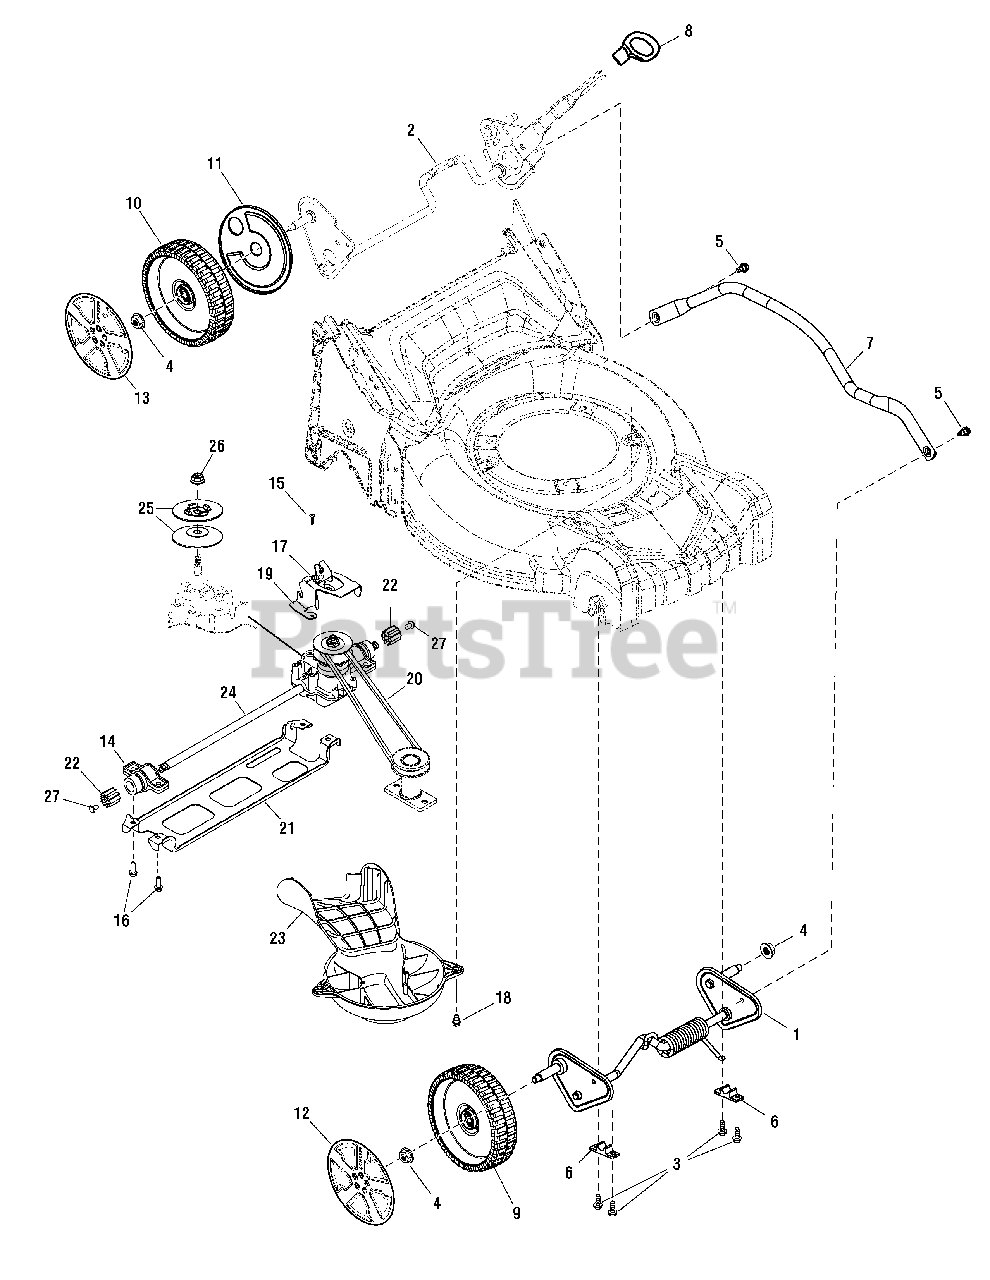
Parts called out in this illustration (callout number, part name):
1	AXLE, Front
2	AXLE, Rear
3	SCREW, 1/4-15X3/4, Self-Tapping, BZ
4	NUT, Hex Flange, Nylock, 3/8-16
5	SCREW, 1/4-20 x 1/2
6	BUSHING, Lock
8	KNOB, Red
9	WHEEL, 180 x 47
10	WHEEL, Drive
11	DUST COVER, Wheel
12	HUBCAP, Front
13	HUBCAP, Rear
14	BEARING ASSEMBLY
15	SCREW, Hex Washer Head, .159 x .43
16	SCREW, 1/4-15 x 1-1/4
18	SCREW, 1/4-20 x 1/2
19	BRACKET
21	SUPPORT
22	GEAR, 10 Tooth
23	COVER, Rear
24	TRANSMISSION
25	PULLEY HALF
26	NUT, Lock
27	GEAR SPACER
